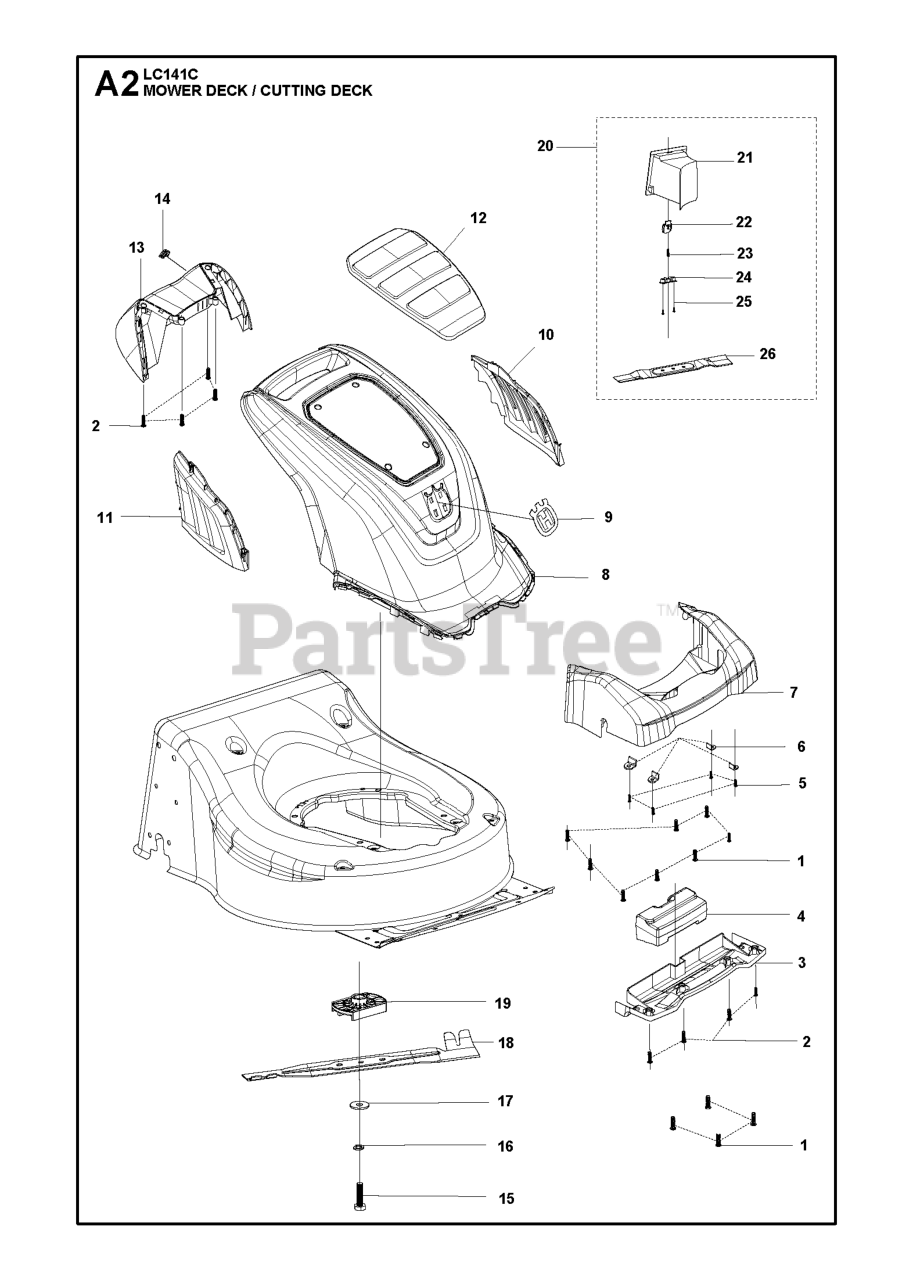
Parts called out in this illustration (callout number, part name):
3	COVER FRONT HANDLE (UNDER SIDE
4	WEIGHT # 25100184101
7	COVER FRONT COVER
9	DECAL LOGO
13	COVER BACK COVER
16	SPRING WASHER
18	MOWER BLADE MULCH 40CM PRODUCT
19	BLADE SUPPORT
21	PLUG 25232600101
26	BLADE 26300349801
